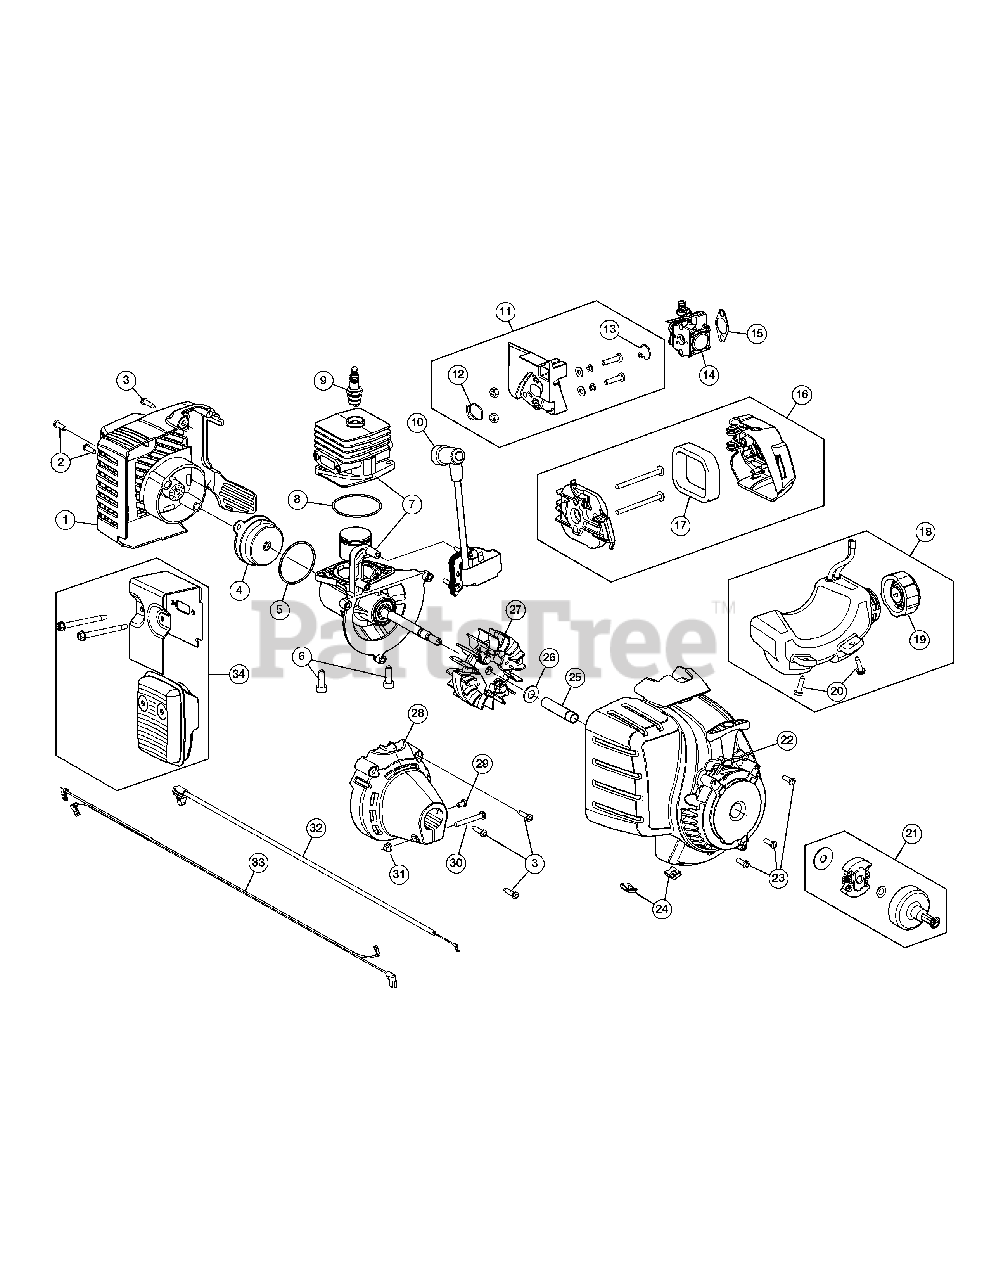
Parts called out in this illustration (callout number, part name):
1	Rear Cover Assembly (Incl. 2 & 3)
2	Rear Housing Screw
3	Cover Screw
4	Electric Starter Cover Assembly
6	Crankcase Bolt
7	Short Block Assembly
8	Crankcase O-Ring
9	Spark Plug
10	Module Assembly
11	Insulator Assembly (Incl. 12 & 13)
12	Insulator O-Ring
13	Carburetor O-Ring
14	Carburetor
15	Air Cleaner Gasket
16	Aircleaner Cover Assembly (Incl. 17)
17	Aircleaner Filter
18	Fuel Tank Assembly (Incl. 19 & 20)
19	Fuel Tank Screw
20	Fuel Tank Cap
21	Clutch Assembly
22	Starter Housing (Incl. 23 & 24)
23	Housing Screw
24	U-shaped Nut
27	Flywheel Assembly
28	Clutch Cover (Incl. 3)
29	Anti-rotation Screw
30	Clamp Screw
31	Clamp Nut
32	Throttle Cable
33	Lead Wires
34	Muffler Assembly
